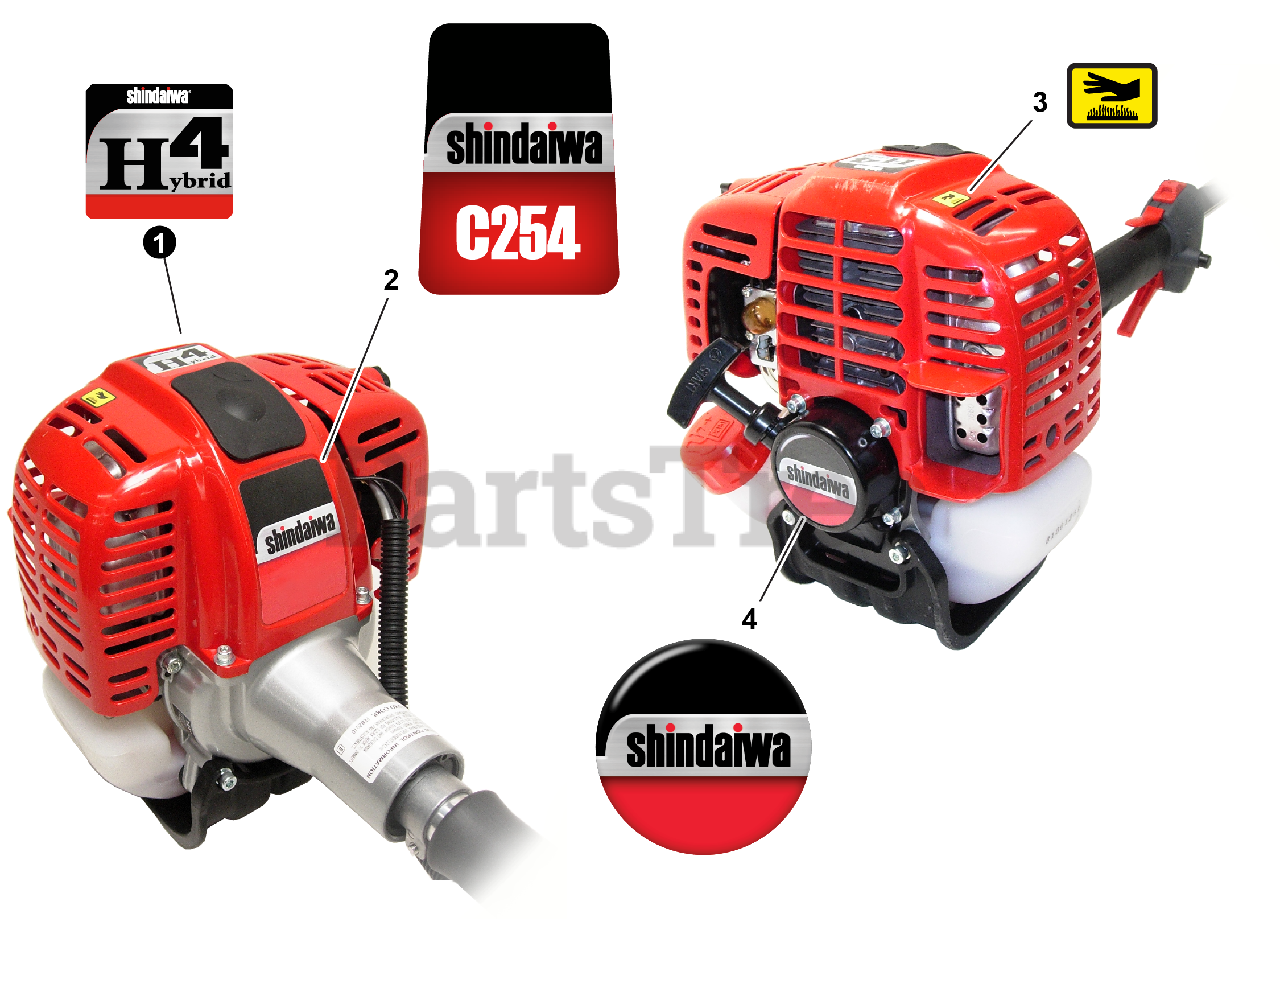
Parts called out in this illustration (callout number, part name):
1	LABEL, shindaiwa H4
2	LABEL, C254
3	LABEL, CAUTION - HOT
4	LABEL, RECOIL STARTER
